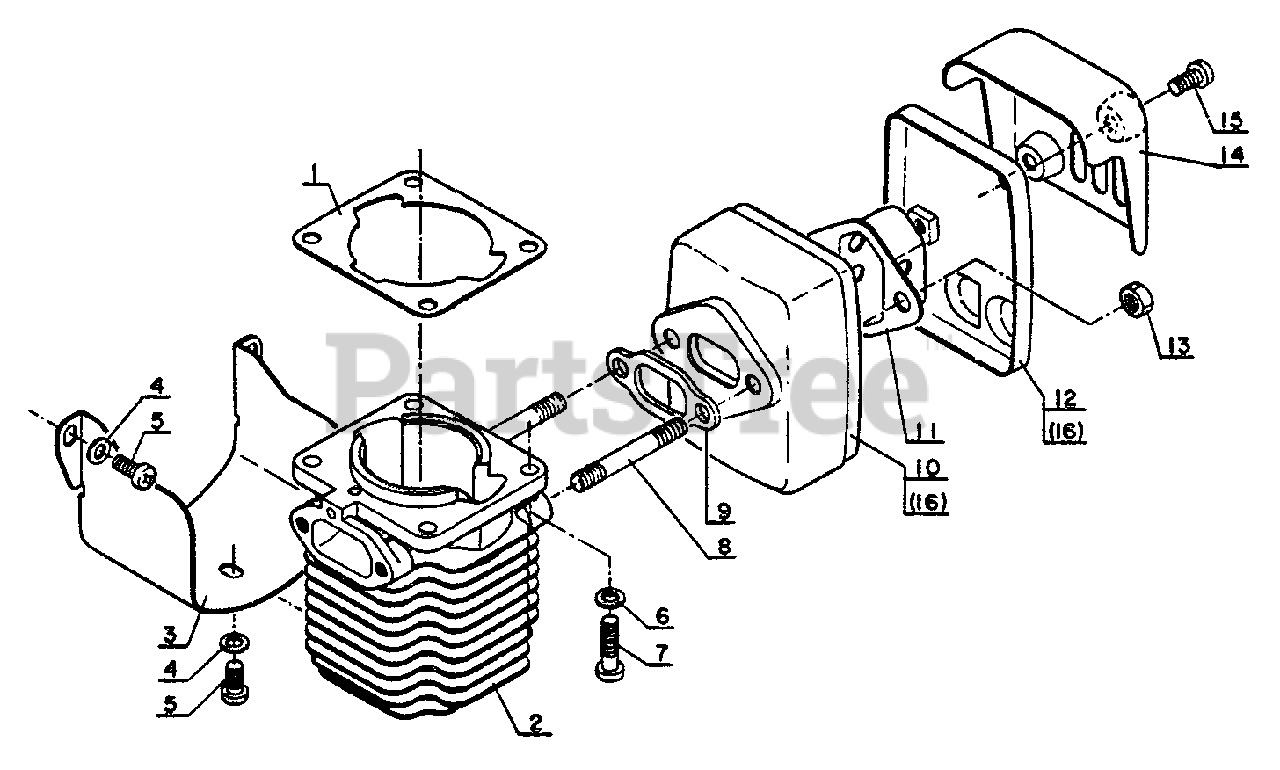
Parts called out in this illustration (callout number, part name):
1	GASKET, CYLINDER
2	CYLINDER
3	SHIELD, CYLINDER
4	WASHER 4 MM
5	SCREW - 4×8
6	WASHER 4 MM
7	SCREW - 4×16
8	STUD
9	GASKET, MUFFLER
10	MUFFLER
11	BAFFLE, MUFFLER
12	LID, MUFFLER
14	COVER, MUFFLER
15	SCREW - 4×8
